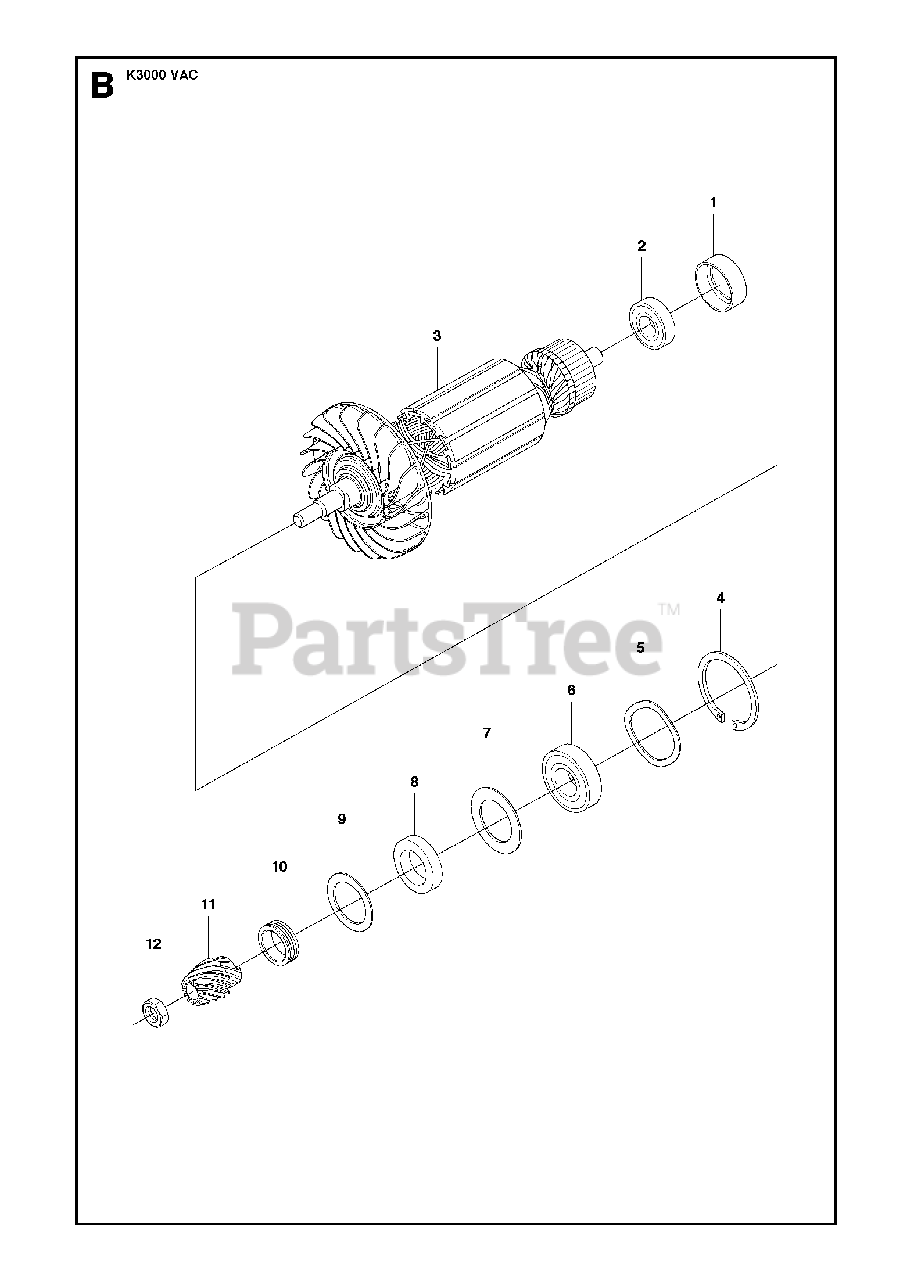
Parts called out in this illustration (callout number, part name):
1	RUBBER BUSHING
3	ROTOR100 - 120V
5	SPRING WASHER
6	BALL BEARING
